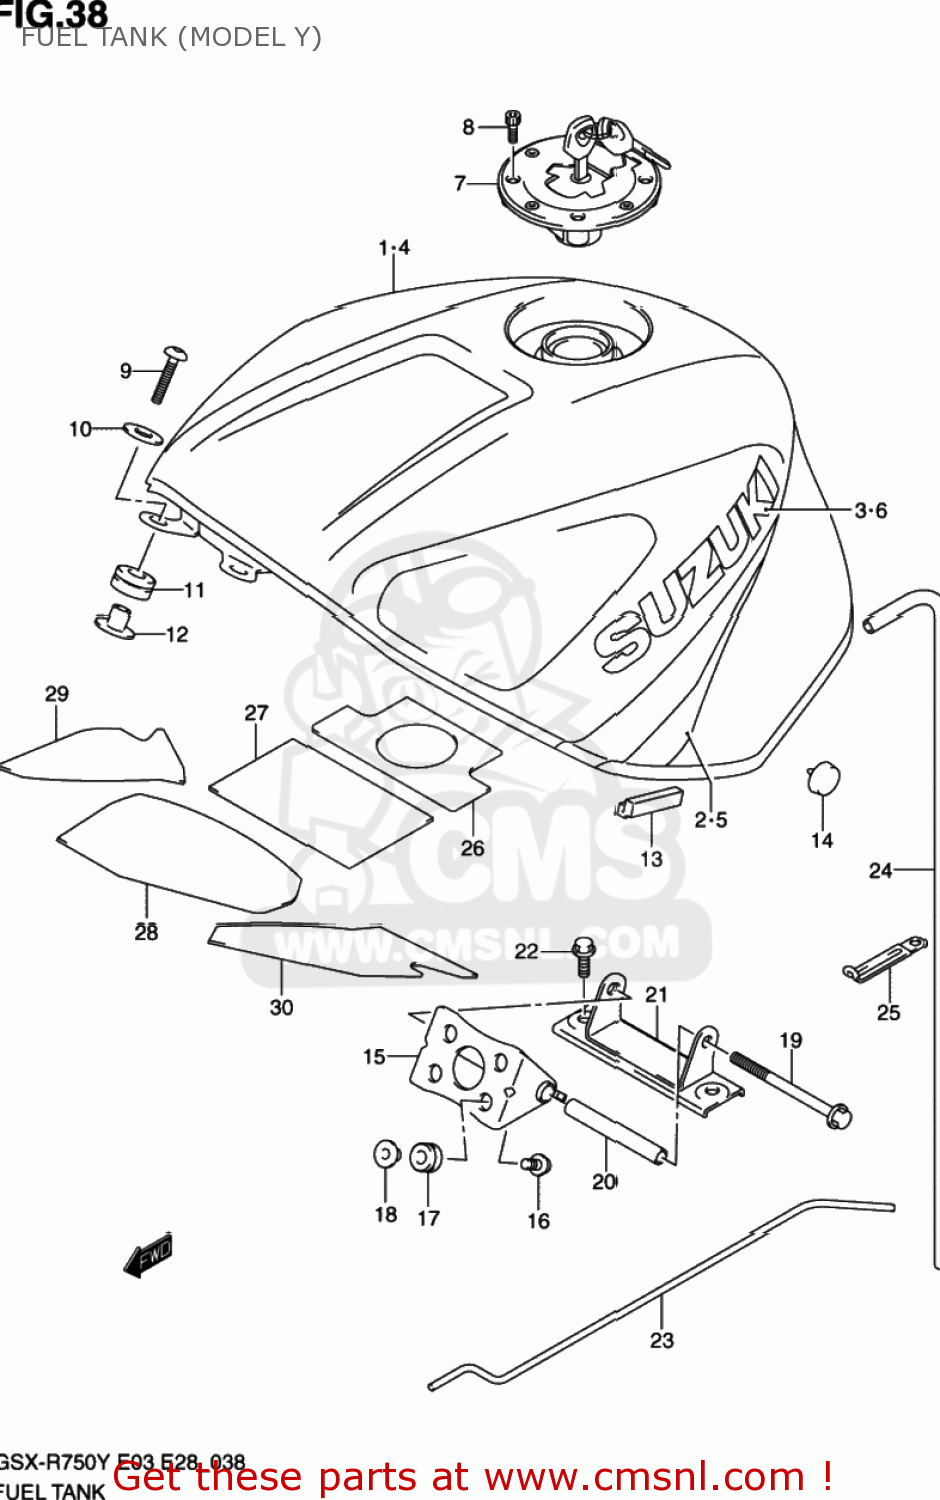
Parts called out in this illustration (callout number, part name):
1	TANK ASSY,FUEL
2	TAPE SET,FUEL TANK
3	EMBLEM,FUEL TANK(WHITE)
4	TANK ASSY,FUEL
5	TAPE SET,FUEL TANK
6	EMBLEM,FUEL TANK
7	CAP SET,FUEL TANK
8	BOLT(5X20)
9	SCREW(6X25)
10	WASHER(6.5X22X1.6)
11	CUSHION,FUEL TANK FR
12	SPACER,FUEL TANK FR
13	CUSHION,FUEL TANK SIDE
14	CUSHION,FUEL TANK SIDE NO.2
15	BRACKET,FUEL TANK NO.1
16	BOLT(6X20)
17	CUSHION
18	WASHER
19	BOLT
20	SPACER,FUEL TANK RR
21	BRACKET COMP,FUEL TANK
22	BOLT
23	STAY,FUEL TANK
24	HOSE,FUEL TANK WATER DRAIN
25	CLAMP(L:65)
26	SHIELD,TANK HEAT RR
27	SHIELD,TANK HEAT CTR
28	SHIELD,TANK HEAT FR CTR
29	SHIELD,TANK HEAT FR,R
30	SHIELD,TANK HEAT FR,L
